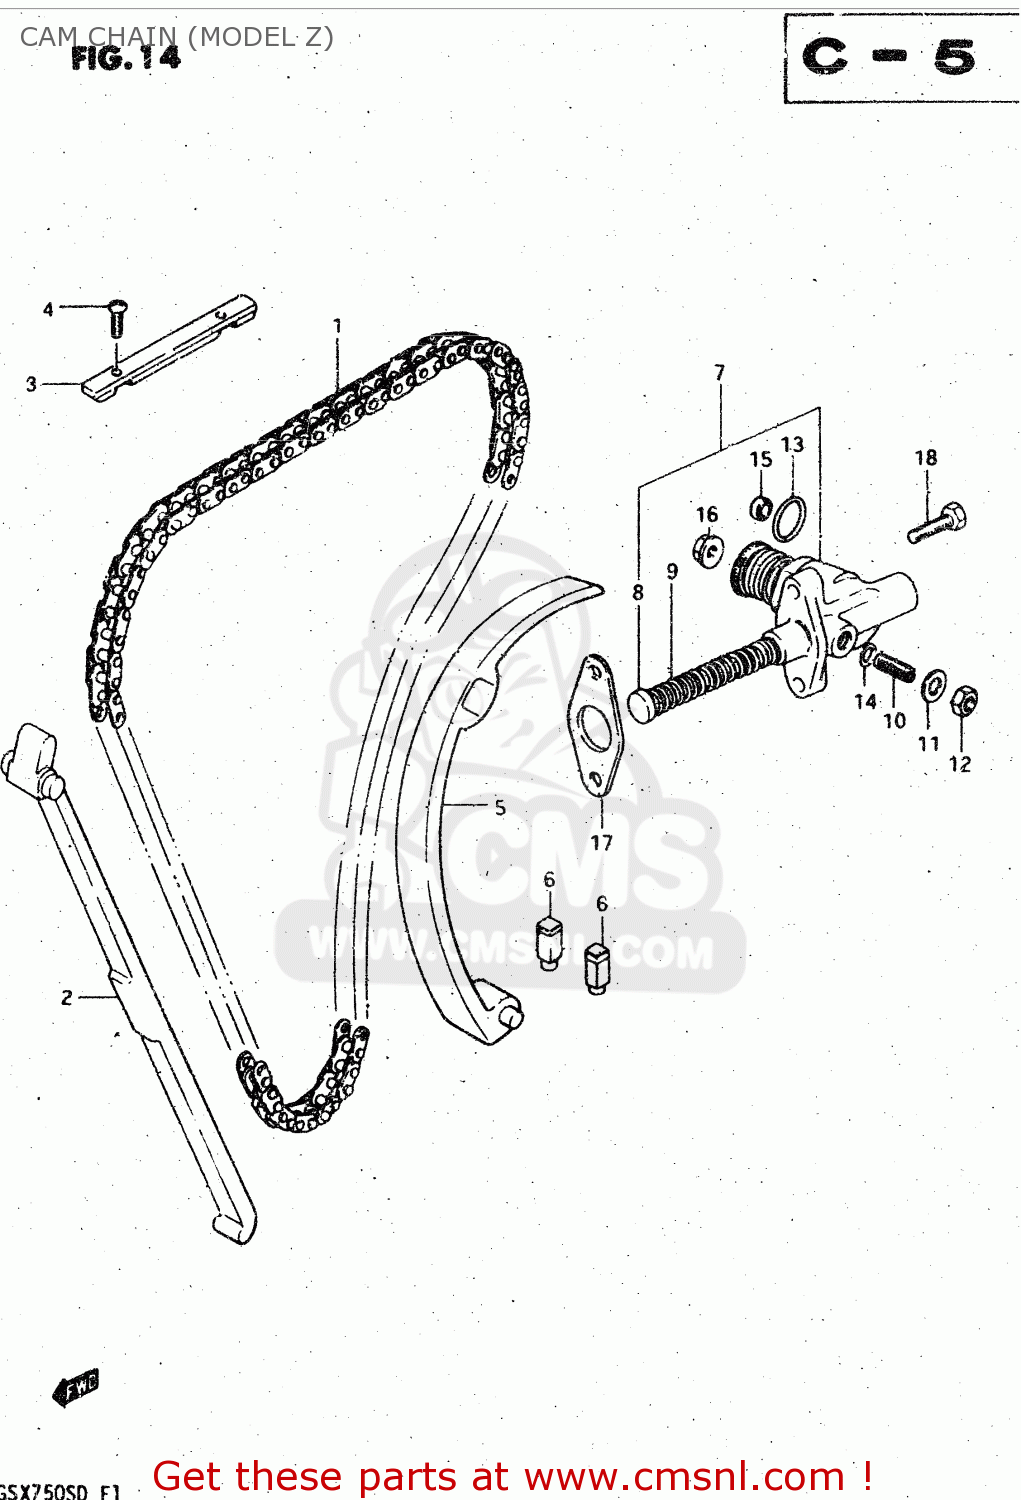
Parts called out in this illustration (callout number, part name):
1	CHAIN,CAMSHAFT DRIVE
2	GUIDE,CAM CHAIN NO.1
3	GUIDE,CAM CHAIN NO.3
4	SCREW
5	TENSIONER,CAM CHAIN
6	CUSHION,CAM CHAIN TENSIONER
7	ADJUSTER,CAM CHAIN TENSIONER
8	ROD,PUSH
9	SPRING
10	SCREW
11	WASHER
12	NUT
13	O RING(D:2.4,ID:20.8)
14	O RING(D:1.9,ID:5.7)
15	SEAL,OIL(10X16X4)
16	NUT
17	GASKET,TENSIONER ADJUSTER (MCA)
18	SCREW (6X25)
